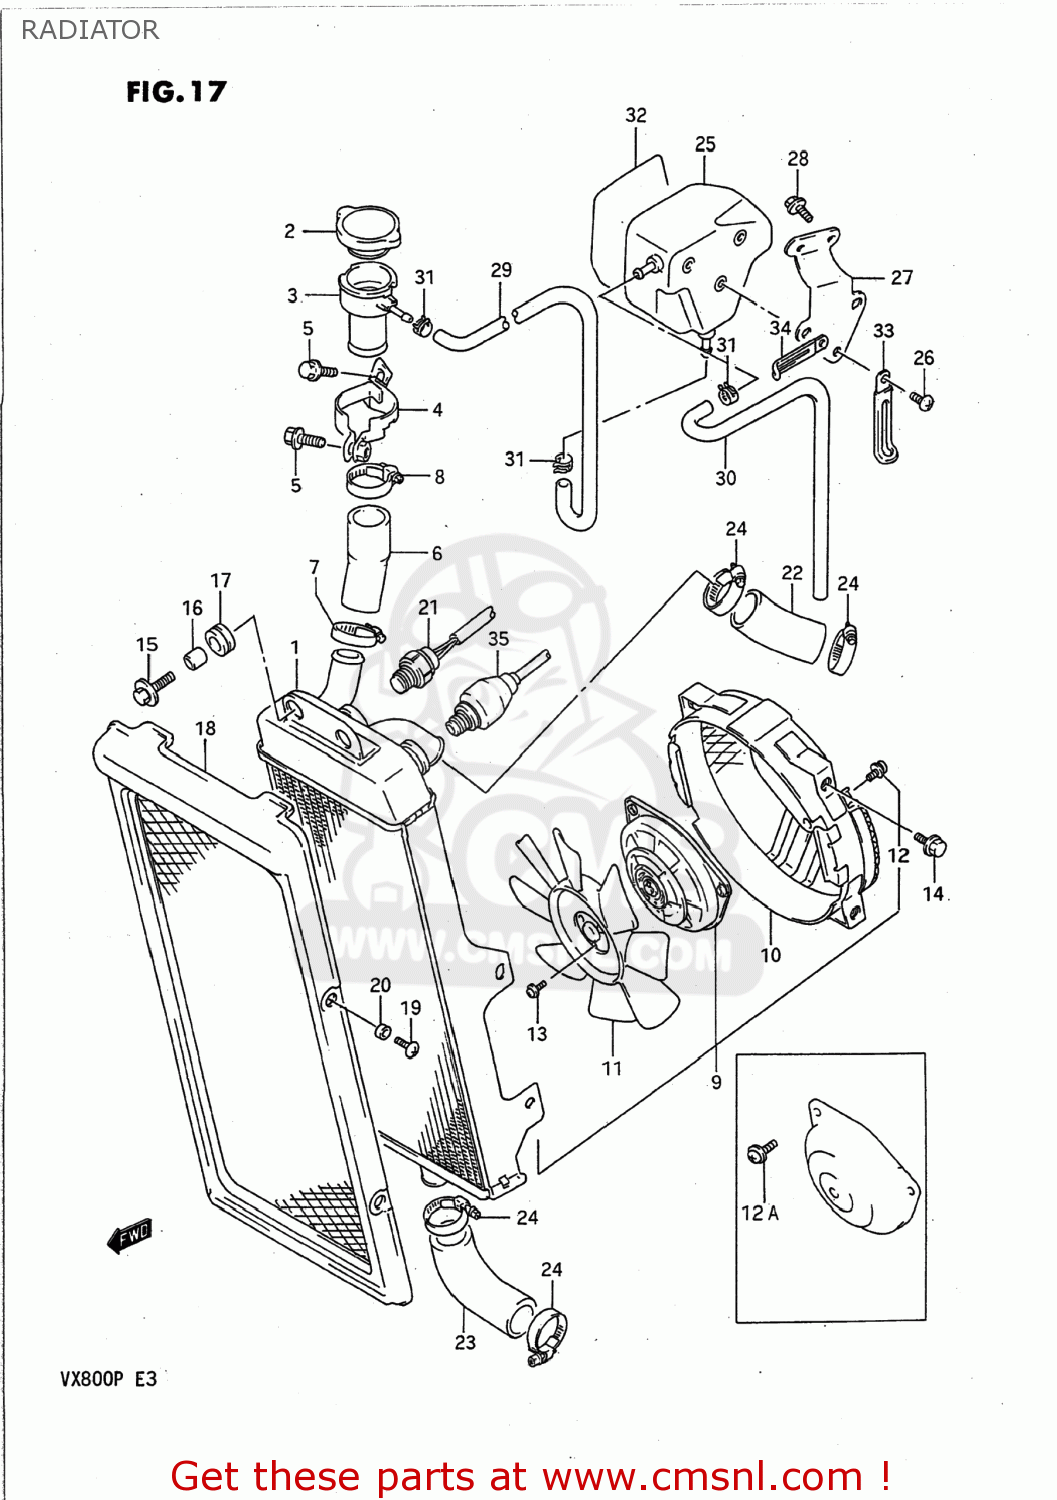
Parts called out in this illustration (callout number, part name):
1	RADIATOR ASSEMBLY,WATER
2	CAP,RADIATOR 1.1
3	CONDUCTION,RADIATOR
4	BRACKET,CONDUCTION
5	BOLT
6	HOSE,CONDUCTION
7	CLAMP
8	CLAMP
9	FAN ASSEMBLY,RADIATOR
10	SHROUD
11	FAN
12	SCREW
12A	BOLT
13	BOLT
14	BOLT
15	BOLT(6X25)
16	SPACER (6.8X10X10)
17	CUSHION
18	COVER COMP,RADIATOR
19	SCREW(6X10)
20	SPACER (6.4X9X3.5)
21	SWITCH,RADIATOR FAN
22	HOSE,RADIATOR INLET
23	HOSE,RADIATOR OUT
24	CLAMP
25	TANK,RESERVOIR
26	SCREW
27	BRACKET,RESERVOIR TANK
28	BOLT 6X20
29	HOSE,RESERVOIR TANK INLET
30	HOSE,RESERVOIR TANK OVERFLOW
31	CLIP
32	EMBLEM,RESERVOIR TANK
33	CLAMP
34	CLAMP L:35
35	SWITCH ASSY,WATER TEMP
